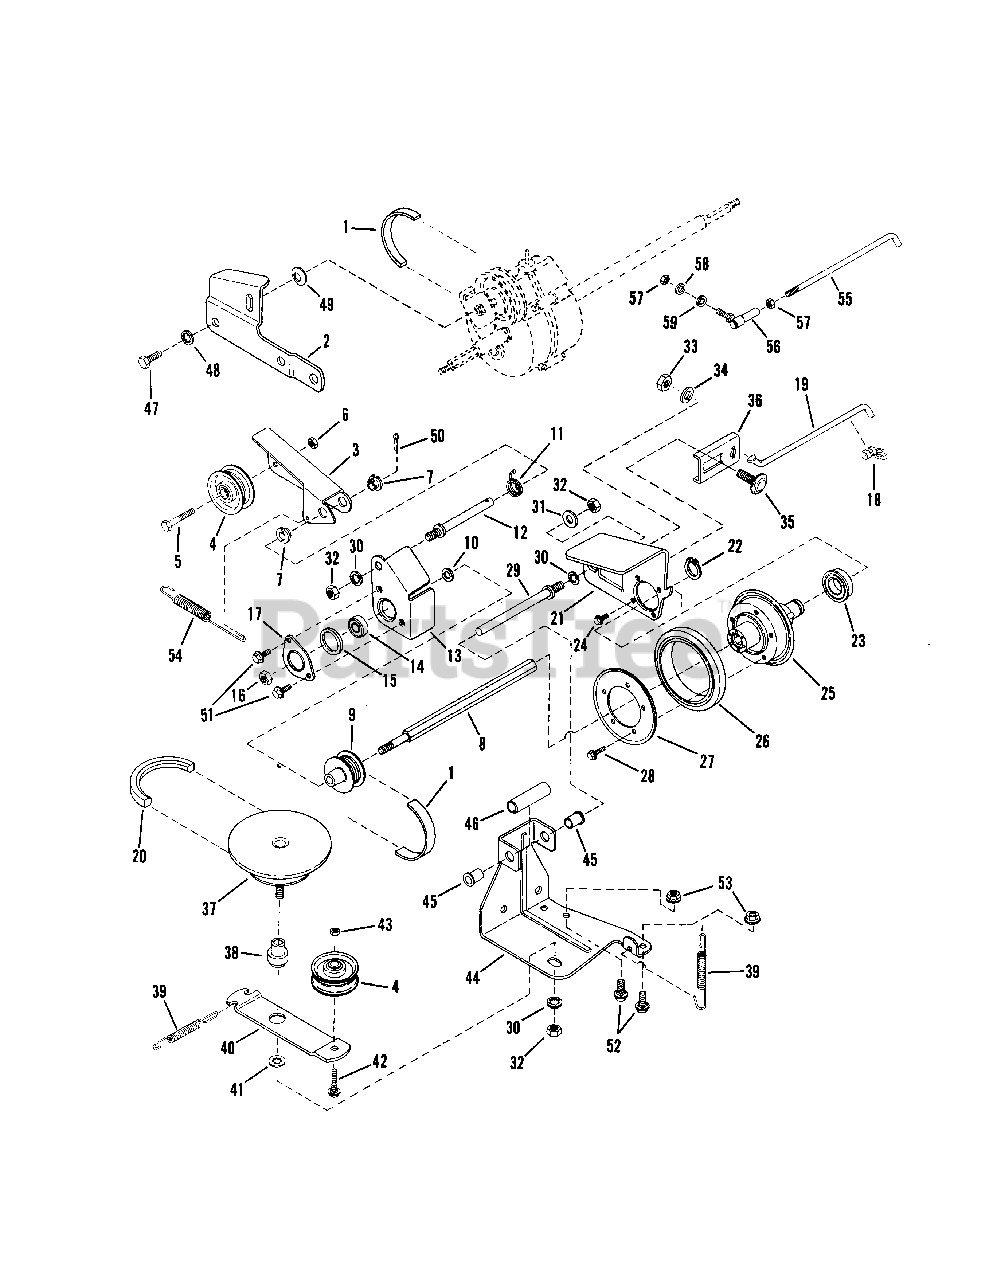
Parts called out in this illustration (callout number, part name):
1	BELT, Poly-Vee
2	LINK, Differential
3	ARM, Clutch Idler
4	PULLEY, Idler
5	CAPSCREW, 1/4-28 x 1-3/6" Hex Head
6	NUT, 1/4-28 Hex Lock
7	BUSHING, 3/8 I.D. Nylon
8	SHAFT, Hex
9	PULLEY
10	WASHER
11	SPRING, Torsion
12	STUD
13	HOLDER, Bearing (Inner Half)
14	BEARING, Ball
15	0-RING
16	NUT, 3/8 Hex Center Lock
17	HOLDER, Bearing (Outer Half)
18	CLIP, 1/4 Right Arc (Transfer Rod)
19	ROD, Transfer
20	BELT, Engine Drive
21	PLATE, Thrust
22	RING, Retaining
23	BEARING, Ball
24	SCREW, #10-32 x 1/4" Self-Tapping Machine
25	ASSEMBLY, Hub
26	RING, Driven (Rubber Disc)
27	PLATE, Ring Retaining
28	SCREW, #10-24 x 1/2" Hex Washer Self-Tap (Torx)
29	GUIDE, Thrust Plate
30	WASHER, 3/8 Internal Tooth Lock
31	WASHER, 3/8" Flat
32	NUT, 3/8-24 Hex
33	NUT, 5/16-18 Hex
34	WASHER, 5/16 Split Lock
35	BOLT, 5/16-18 x 3/4 Carriage
36	CONNECTOR, Transfer Rod
37	ASSEMBLY, Drive-Disc
38	BUSHING
39	SPRING (Wheel Drive & Idler)
40	ARM, Idler
41	RETAINER, 3/8 Bolt
42	BOLT, 1/4-20 x 1-1/4" Carriage
43	NUT, 1/4-20 Hex Center Lock
44	BRACKET, Deck
45	BUSHING, Flange
46	SPACER
47	SCREW, 5/16-18 x 1/2" Hex Head Cap
48	WASHER, 5/16 Internal Tooth Lock
49	WASHER, Spring
50	COTTER-PIN, 3/32 x 1/2"
51	SCREW, 1/4-20 x 1/2" Self-Tapping
52	BOLT, 5/16-18 x 5/8" Short Neck Carriage
53	NUT,5/16-18 Hex Flange Lock
54	SPRING, Clutch
55	LINK, Transfer ('89 Models & Later)
56	JOINT, Ball ('89 Models & Later)
57	NUT,1/4-28 Hex('89 Models & Later)
58	WASHER, 1/4 Flat ('89 Models & Later)
59	WASHER, 1/4 internal Tooth Lock ('89 Models & Later)
